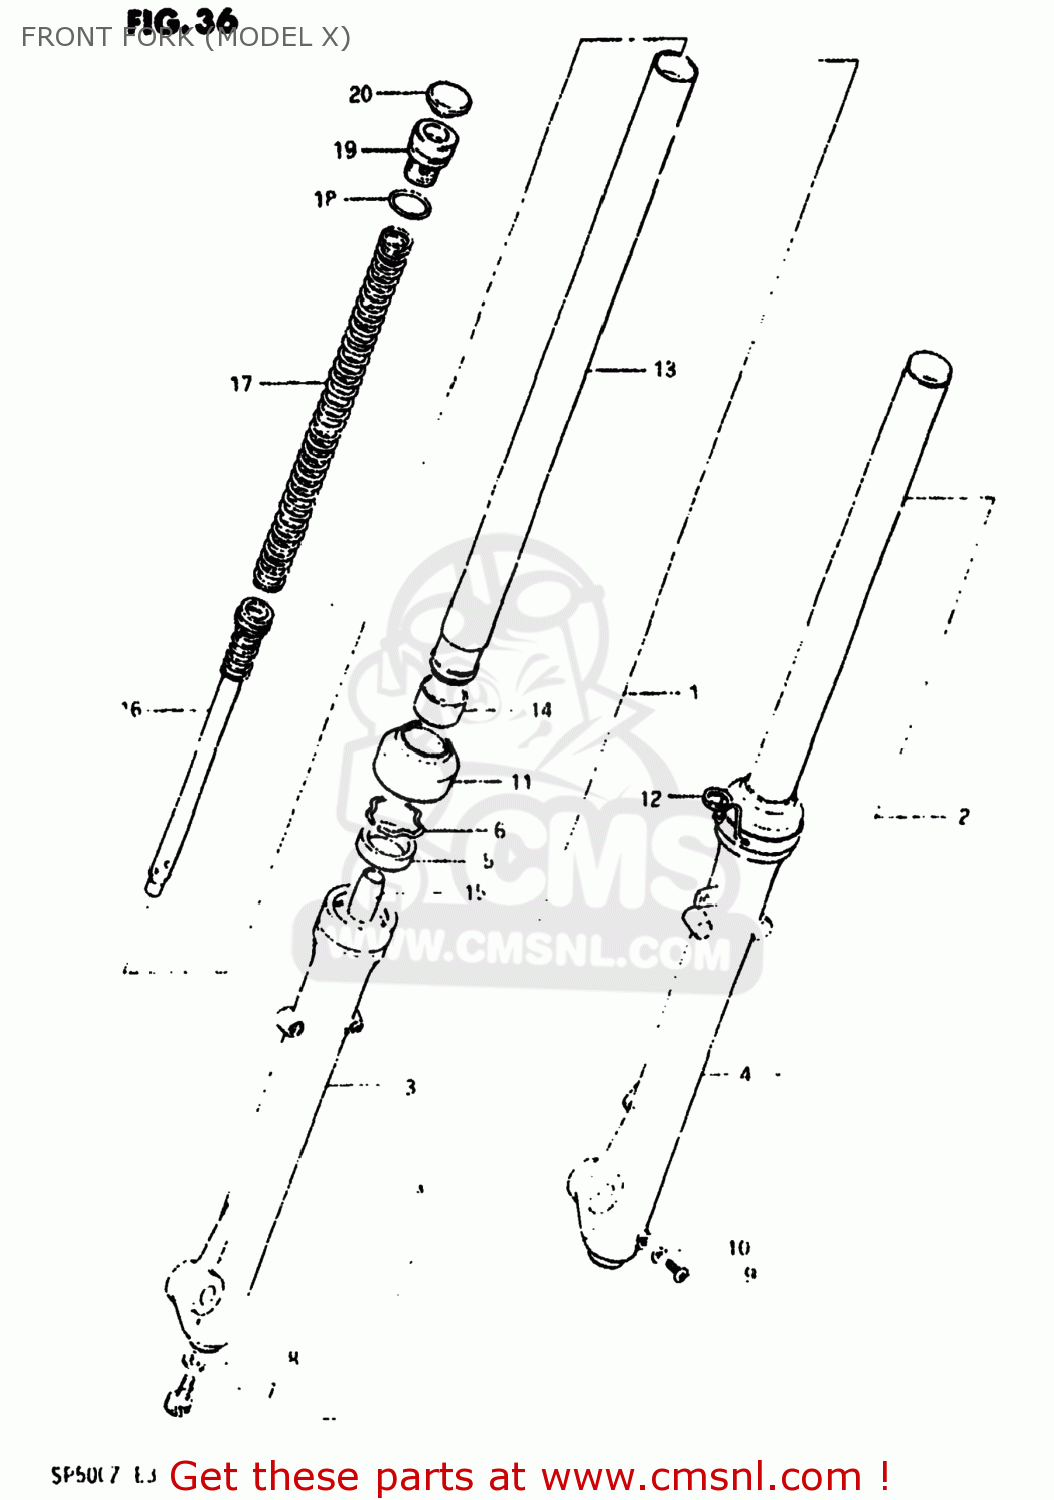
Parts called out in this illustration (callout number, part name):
1	DAMPER ASSEMBLY,RIGHT
2	DAMPER ASSEMBLY,LEFT
3	TUBE,OUTER,RIGHT
4	TUBE,OUTER,LEFT
5	OIL SEAL,FRONT FORK
6	7
7	BOLT,FORK CYLINDER(10X25)
8	GASKET (NAS)
9	SCREW
10	GASKET,DRAIN,PLUG (NAS)
11	SEAL,DUST
12	BAND,FRONT FORK COVER
13	TUBE,FORK,INNER
14	PISTON
15	PIECE,OIL LOCK
16	CYLINDER,FRONT FORK
17	SPRING,FRONT FORK
18	O RING
19	CAP,FORK INNER TUBE
20	CAP,FRONT FORK
